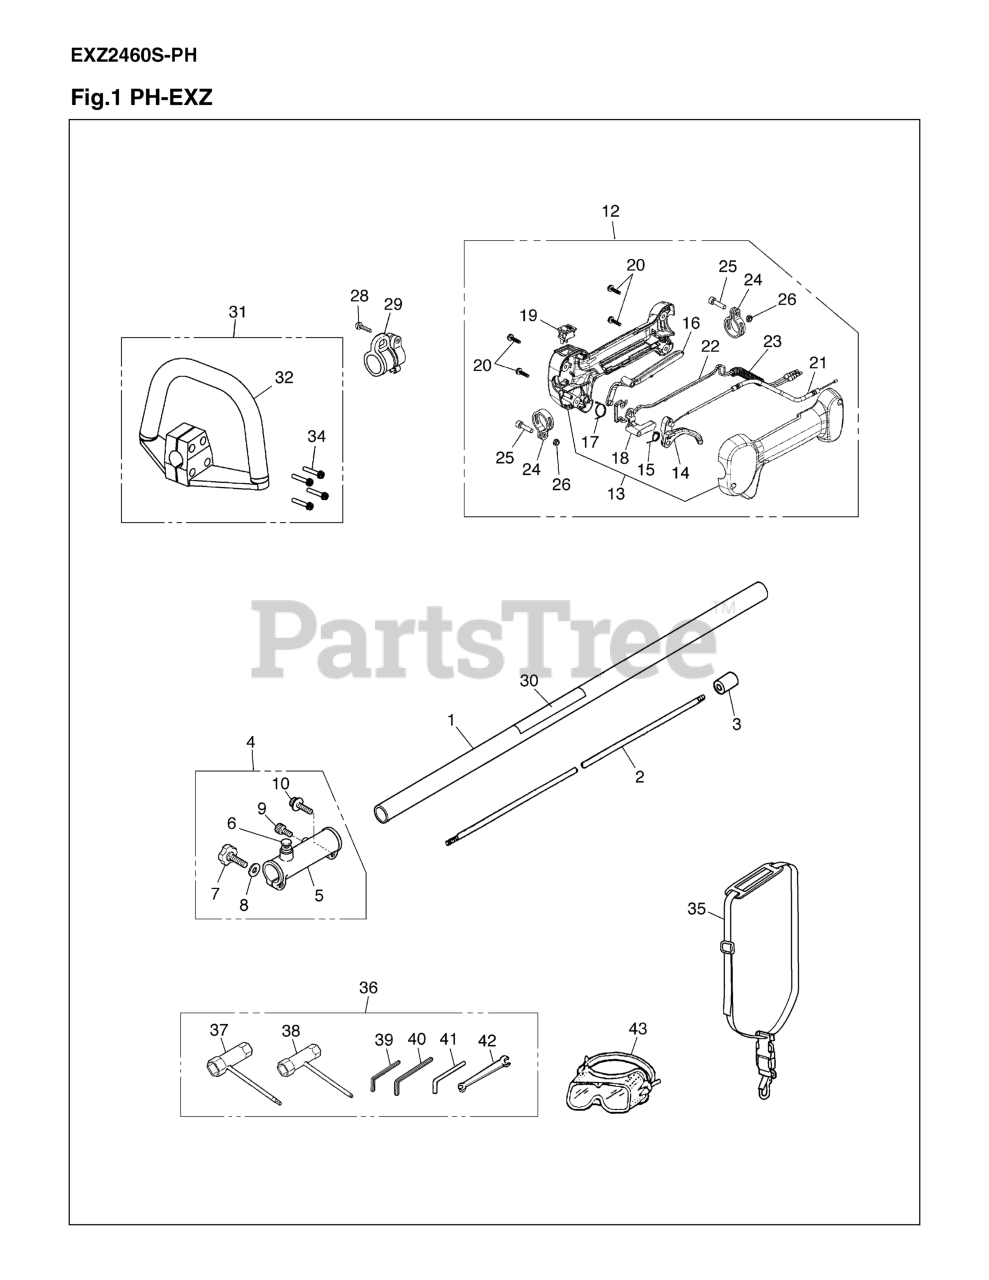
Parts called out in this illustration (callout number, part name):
1	PIPE-C
3	SPACER
4	JOINT ASSY
5	JOINT
6	STOPPER COMPLETE
7	BOLT, KNOB
8	WASHER,M8x2.3(RP
9	BOLT
10	BOLT,TORX
12	GRIP ASSY
13	GRIP, HALF SET
14	LEVER, THROTTLE
15	SPRING, THROTTLE
16	LEVER FOR GRIP (
18	LEVER JOINT
22	CORD - C
25	BOLT (RPLS 28501
26	NUT
28	HANGER COMP.
29	SCREW, M5x20 (RP
30	NAME PLATE
31	HANDLE ASSY. (RP
32	HANDLE T
35	STRAP ASSY
36	TOOL SET
37	SOCKET
40	WRENCH (TOOL)
41	BAR
42	SPANNER,8 x 10(R
43	GOGGLExxx (RPLS
